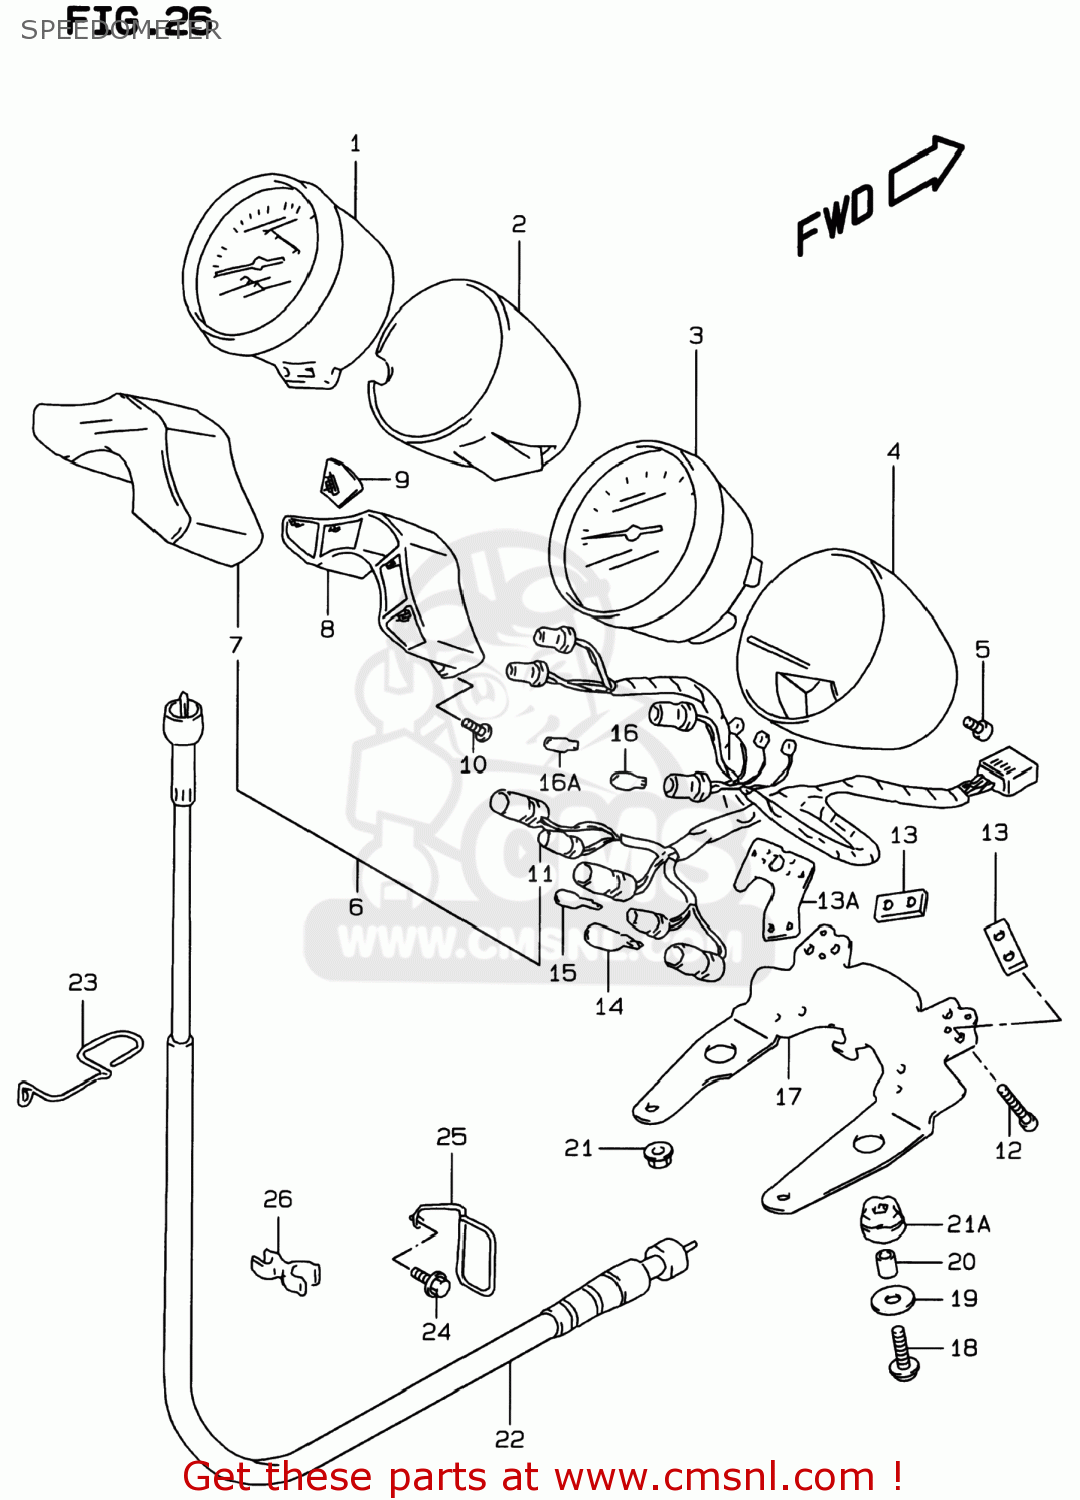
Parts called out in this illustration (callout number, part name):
1	SPEEDOMETER(MILE/KILO)
2	LWR CASE,SPEEDOMETER
3	TACHOMETER
4	LOWER CASE,TAC
5	SCREW
6	BOX,PILOT
7	CASE,UPR
8	INNER CASE
9	LENS SET,PILOT
10	SCREW
11	SOCKET
12	SCREW
13	PLATE
13A	PLATE
14	BULB(12V3.4W,T10,BF175-01450A)
15	BULB(12V3W,WB371,T7)
16	BULB(12V1.7W,WB372,T7)
16A	BULB(14V,0.84W)
17	BRACKET,METER
18	BOLT
19	WASHER(6.5X20X1.6)
20	SPACER(6.5X9X15.5)
21	NUT
21A	CUSHION
22	CABLE ASSY,SPEEDOMETER
23	GUIDE,SPEEDOMETER CABLE
24	BOLT
25	GUIDE,SPEEDOMETER CABLE
26	CLIP
